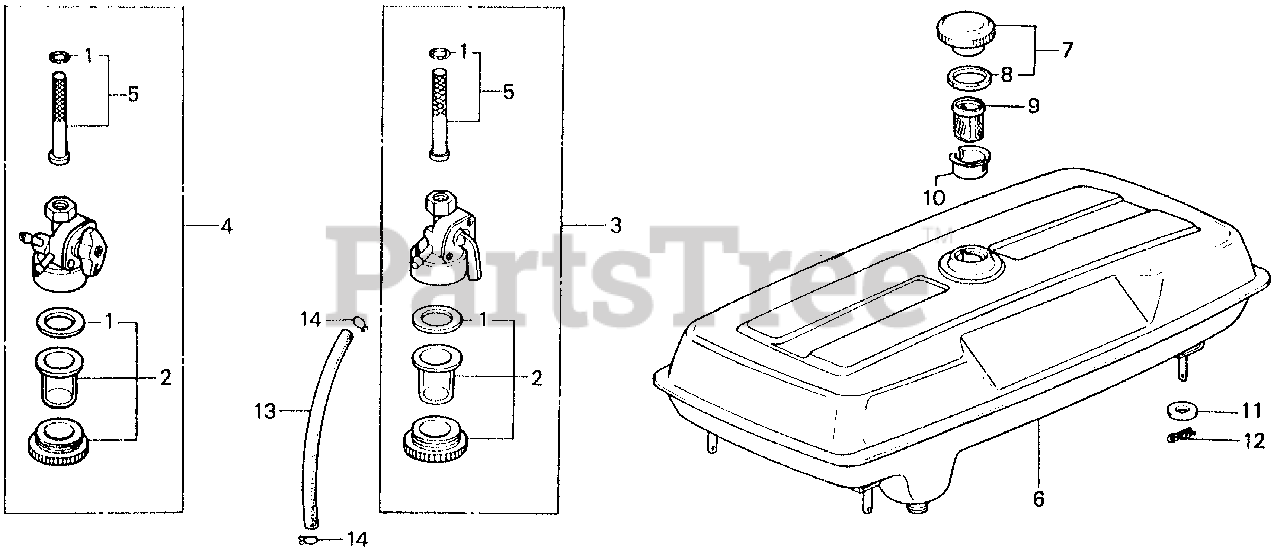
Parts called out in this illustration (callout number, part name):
1	GASKET SET, PETCOCK
2	CUP SET, FUEL STRAINER
3	PETCOCK ASSY.
5	SCREEN SET
6	TANK, FUEL *NH31* (MCKINLEY WHITE)
7	CAP, FUEL FILLER (BLACK)
7	CAP, FUEL FILLER
8	GASKET, FUEL FILLER CAP (39X58X3)
9	FILTER, FUEL
10	HOLDER, FUEL FILTER
11	WASHER, FLAT (20MM)
12	PIN, LOCK (8MM)
13	BULK HOSE, FUEL (4.5X3000) (4.5X135)
14	CLIP, TUBE (B8)
